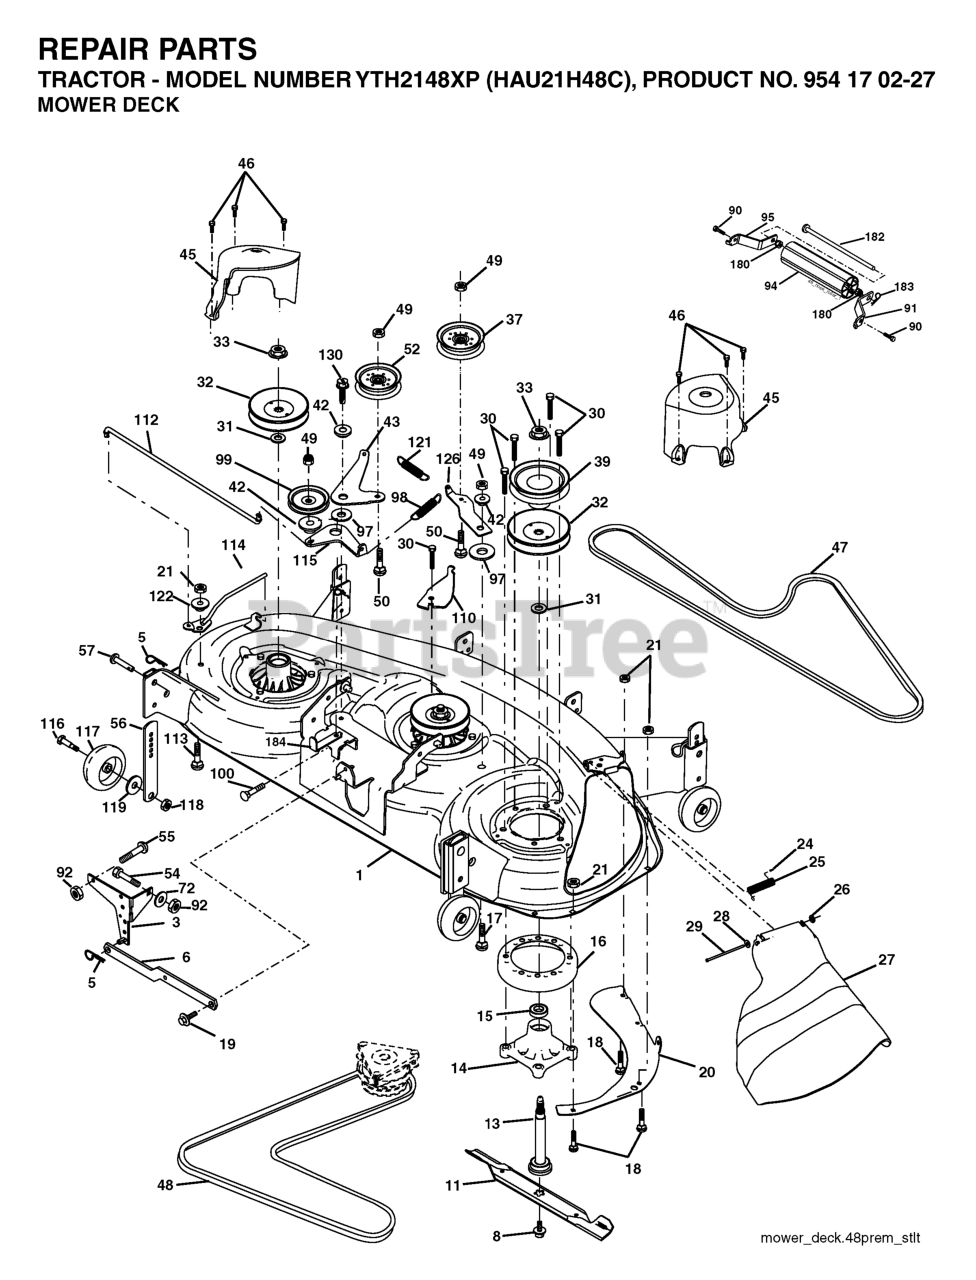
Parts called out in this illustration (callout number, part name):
1	DECK WELDMENT MOWER, 48
3	BRKT ASM SWAY BAR
5	RETAINER-SPRNG RB
6	BAR SWAY DECK
8	BOLT 7/16 ASM BLADE
11	48" HI-LIFT BLADE
13	SHAFT ASM W/LOWER BEARING
14	HOUSING, MANDREL 48"
16	STRIPPER.MANDREL.ROUND.BLACK
17	BOLT
18	BOLT
19	BOLT SHD 5/16-18
20	BAFFLE, VORTEX MWR
21	LOCKNUT
24	CAP-SLEEVE LT
25	SPRING, TORSION
26	NUT PUSH M
27	DEFLECTOR SUBS TO 532 180655
28	Washer 11/32 x 5/8 x 16 Ga SD
29	ROD.HINGE
30	SCREW, WASHER HEAD
31	WASHER.SPACER.MANDREL
32	PULLEY, MANDREL
33	NUT, FLG TOPLOCK 9/16"
36	WASHER
37	PULLEY.IDLER.FLAT
39	PULLEY.DRIVEN.DECK.48'
42	SPACER RETAINER
43	ARM, IDLER SECONDARY
45	COVER.MANDREL.DECK.48"
46	SCREW.1/4-20X5/8
47	V-BELT, 48"SECONDARY
48	V-BELT PRIMARY 48"
49	NUT LOCK FLG 3/8-16 UNC
50	BOLT.3/8-16X1.50
52	PULLEY.IDLER.FLAT.46.PR.DR.
55	BOLT D
56	BAR.ADJUST.WHEEL.ANTI.SCALP.BL
57	RIVET.PIN.HEAD.YELLOW.
72	WASHER
90	BOLT RB
91	BRKT.NOSEROLLER.RH.48"
92	NUT
94	NOSE ROLLER 48"
95	BRKT.NOSEROLLER.LH.48"
98	SPRING PRIMARY DRIVE
99	IDLER PULLEY
110	ARM, SPRING SECONDARY
112	LEVER, TENSION RELIEF LINK
113	BOLT.CARR.SQNK.5/16-18UNC.X3/4
114	TENSION ASM RELIEF LEVER
115	ARM, SPRING TENSION RELIEF
116	BOLT.SHOULDER.3/8-16X3-5/8.
117	RP WHEEL. GUAGE RALLY
118	LOCKNUT
119	WASHER.5/16.FLAT.STE.STD.
121	SPRING.DRIVE.SECONDARY.48".DEC
122	BUSHING, PIVOT TENSION RELIEF
126	ARM, IDLER PRIMARY DECK
130	SCREW 3/8-16X1
180	NUT.71038.31-18.HEX.NYLOCK
182	ROD.ROLLER.NOSE.NARROW.48"
183	SPRING RETAINER
184	KEEPER BELT IDLER PLATED
